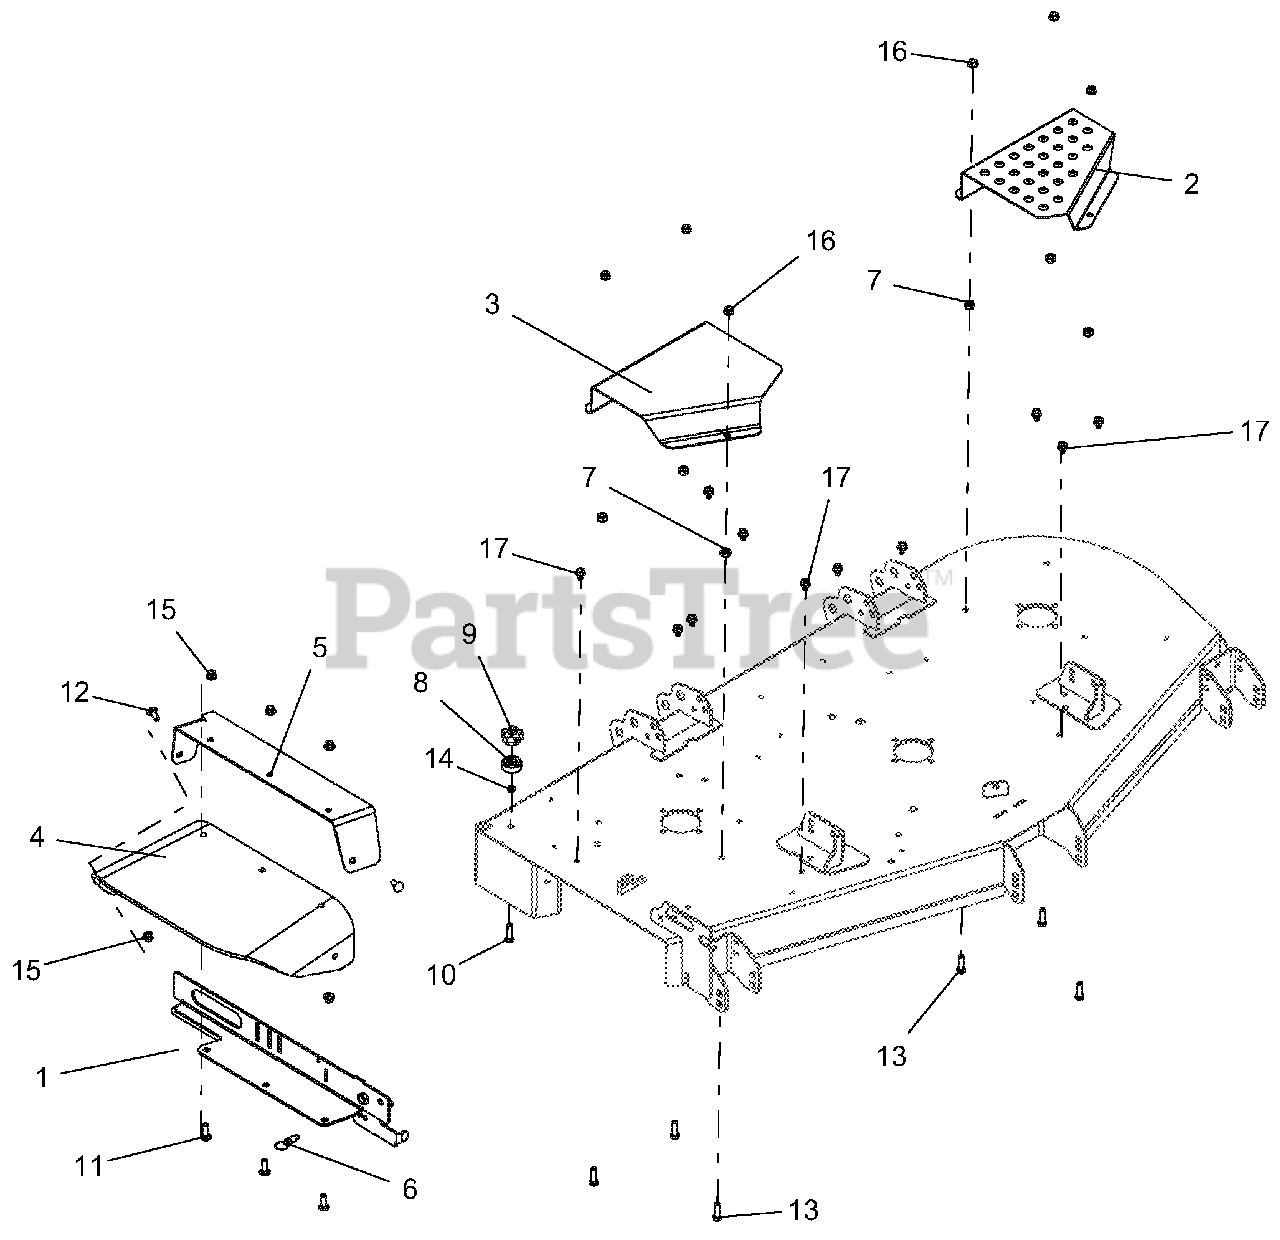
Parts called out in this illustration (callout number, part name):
1	WLDMT, 52"-60" DISCH CHUTE MTG-RED
2	GUARD, 60" LH DECK BELT-BLACK
3	GUARD, 60"-66" RH DECK BELT-BLACK
4	CHUTE, RUBBER DISCHARGE
5	KIT, PT DISCH CHUTE SUPT W/SAFETY DECALS-RED
6	PULL PIN,.50-13THDX.310 PLNGR
7	NUT-HEAVY HEX .38-16 YWZC
8	BUMPER, RECESSED 1.50 X .63 W/.31 HOLE
9	KNOB, CLAMPING
10	BLT-RDHDSQNK .31-18X1.50 G5 YWZC
11	BLT-RDHDSQNK .38-16X1.25 G5 YWZC
12	BLT-RDHDSQNK .38-16X1.00 G5 YWZC
13	BLT-HEX .38-16X1.25 GR5 YWZC
14	NUT-LK-CTR .31-18 YWZC
15	NUT-LK-NYL-FLG .38-16 YWZC
16	@NUT-SPNLK-FLG .375-16 YWZC
17	SCR-TAP .38-16X.50 HWH TR YWZ
